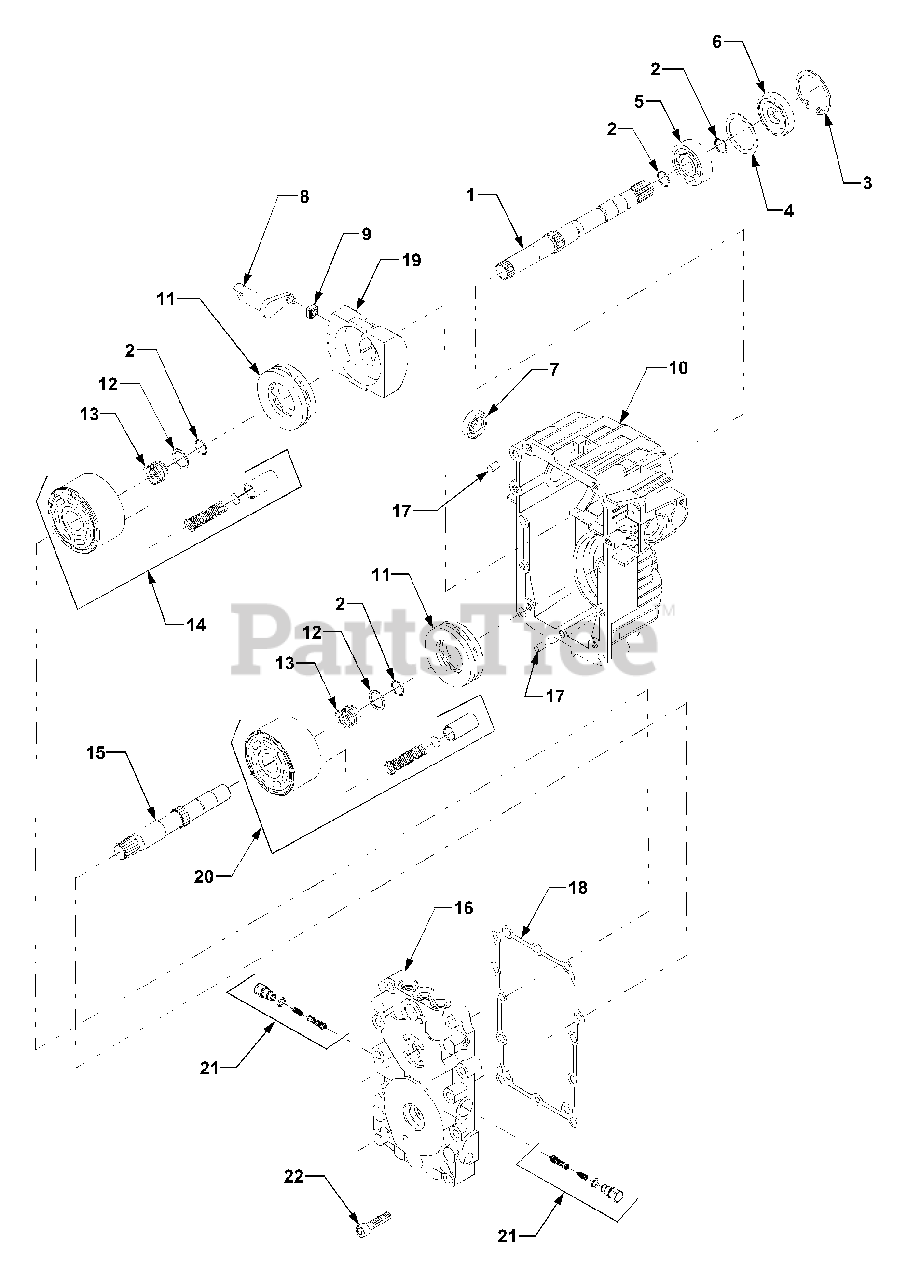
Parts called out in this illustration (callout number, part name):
1	Shaft, Pump
2	Ring, Wire Retaining
3	Ring, Retaining
5	Bearing, Ball
6	Seal, Lip
8	Arm, Trunnion
9	Guide, Slot
10	Housing Assembly
11	Bearing Assembly, Thrust Ball
12	Washer, Block Thrust
13	Spring, Block
14	Kit, Pump Cylinder Block
15	Shaft, Motor
16	Kit, Center Section
18	Gasket, Center Section
19	Swashplate, Variable
20	Kit, Motor Cylinder Block
21	Shock Valve
22	Screw, Socket Head Cap
